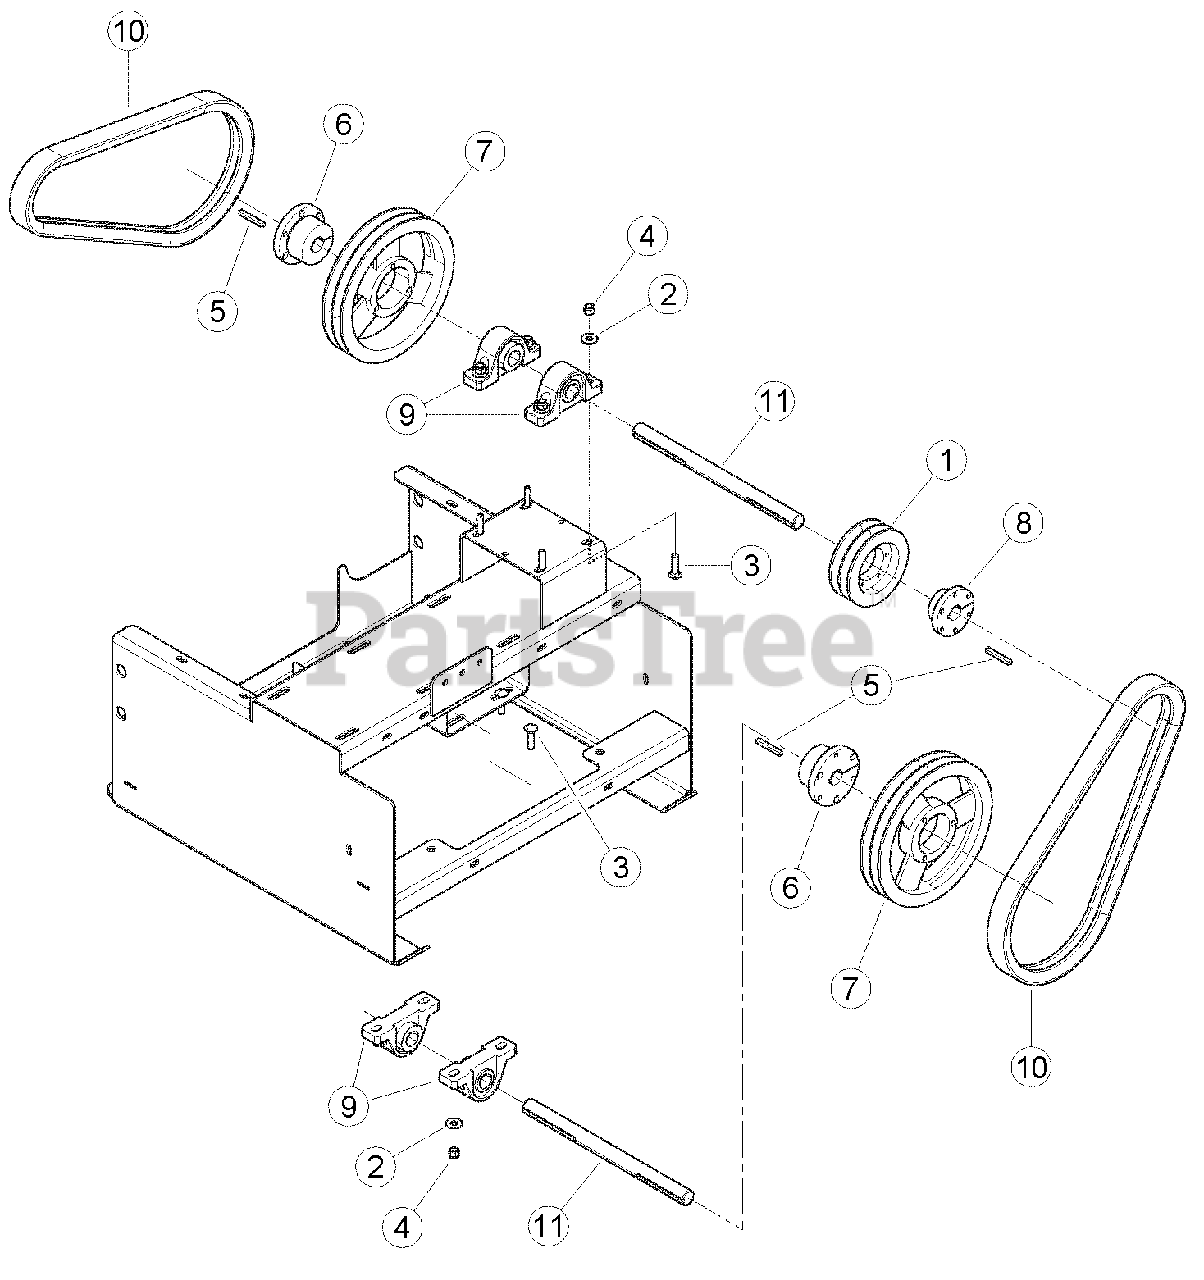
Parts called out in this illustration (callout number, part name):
1	SHEAVE, 2B4.8 SDS
2	WASHER, 3/8 FLAT ZP
3	BOLT, 3/8 X 1-1/2 CRG GR5 NC ZP
4	NUT, 3/8 NE NYLOCK ZP
5	KEY, 1/4 SQUARE X 2 LONG PLAIN
6	BUSHING, 1" SK
7	SHEAVE, 2B9.4 SK
8	BUSHING, SDS 1"
9	PILLOW BLOCK BEARING 1"
10	BELT, 2RB47
11	JACKSHAFT, CHIPPER
